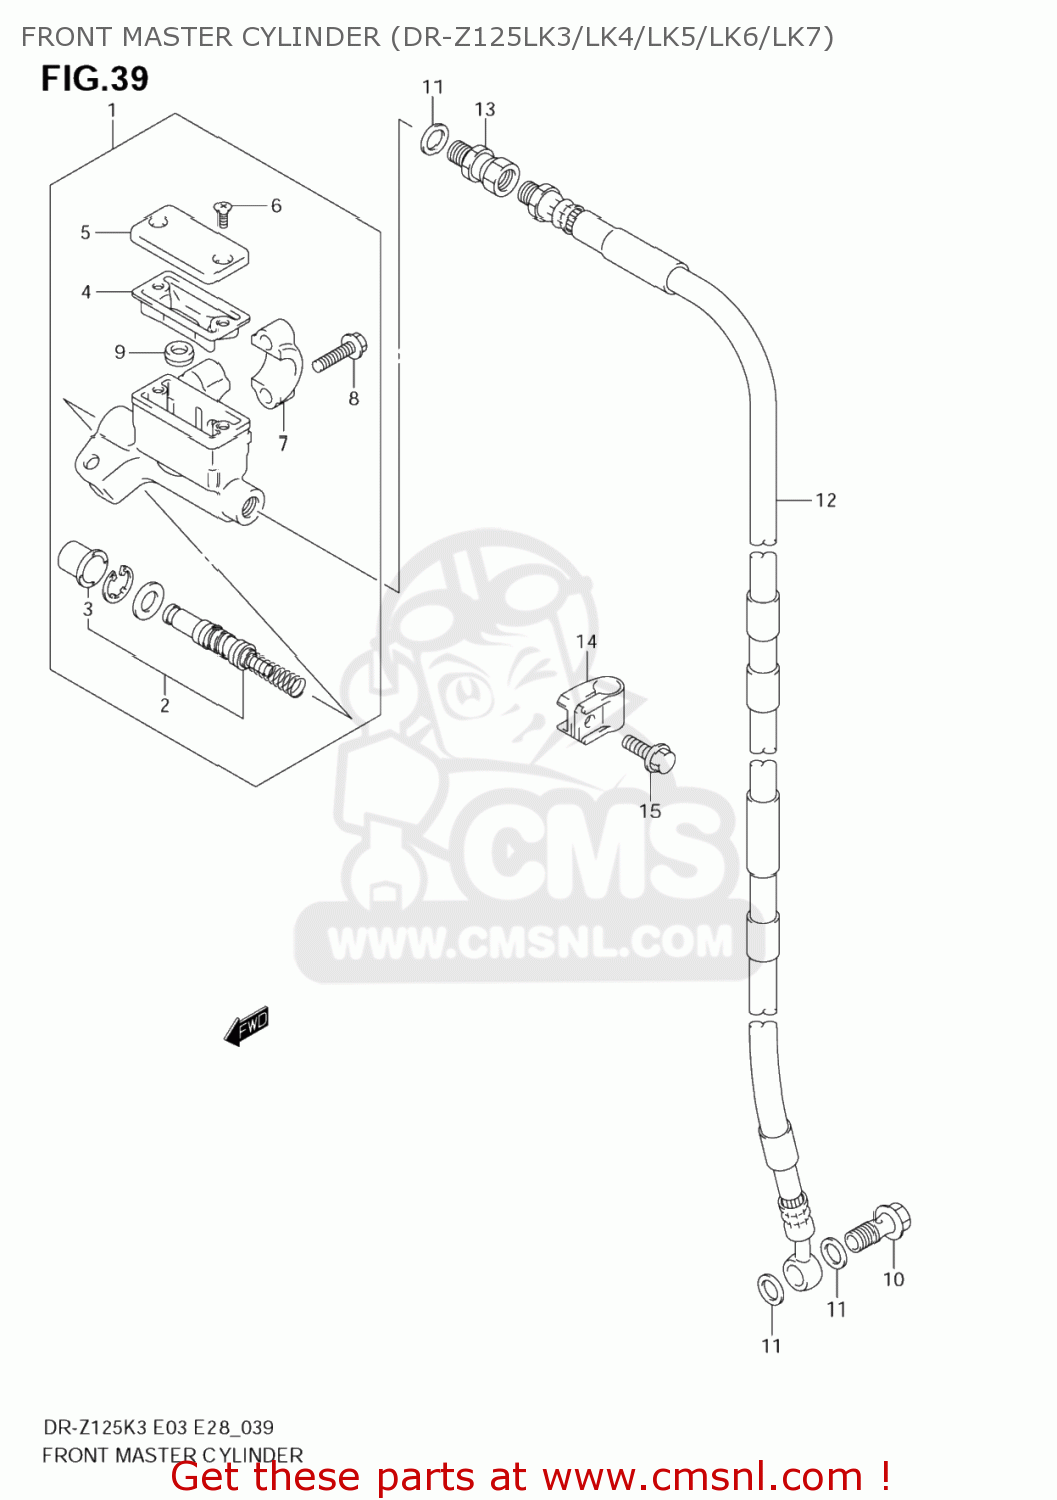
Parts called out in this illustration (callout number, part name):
1	CYLINDER ASSY,FR MASTER
2	PISTON & CUP SET
3	BOOT
4	DIAPHRAGM
5	CAP
6	SCREW
7	HOLDER
8	BOLT
9	SEPARATOR
10	BOLT UNION
11	WASHER(10X15X1.5)
12	HOSE, FRONT BRAKE
13	ADAPTOR,BRAKE HOSE
14	CLAMP,FR BRAKE
15	BOLT
